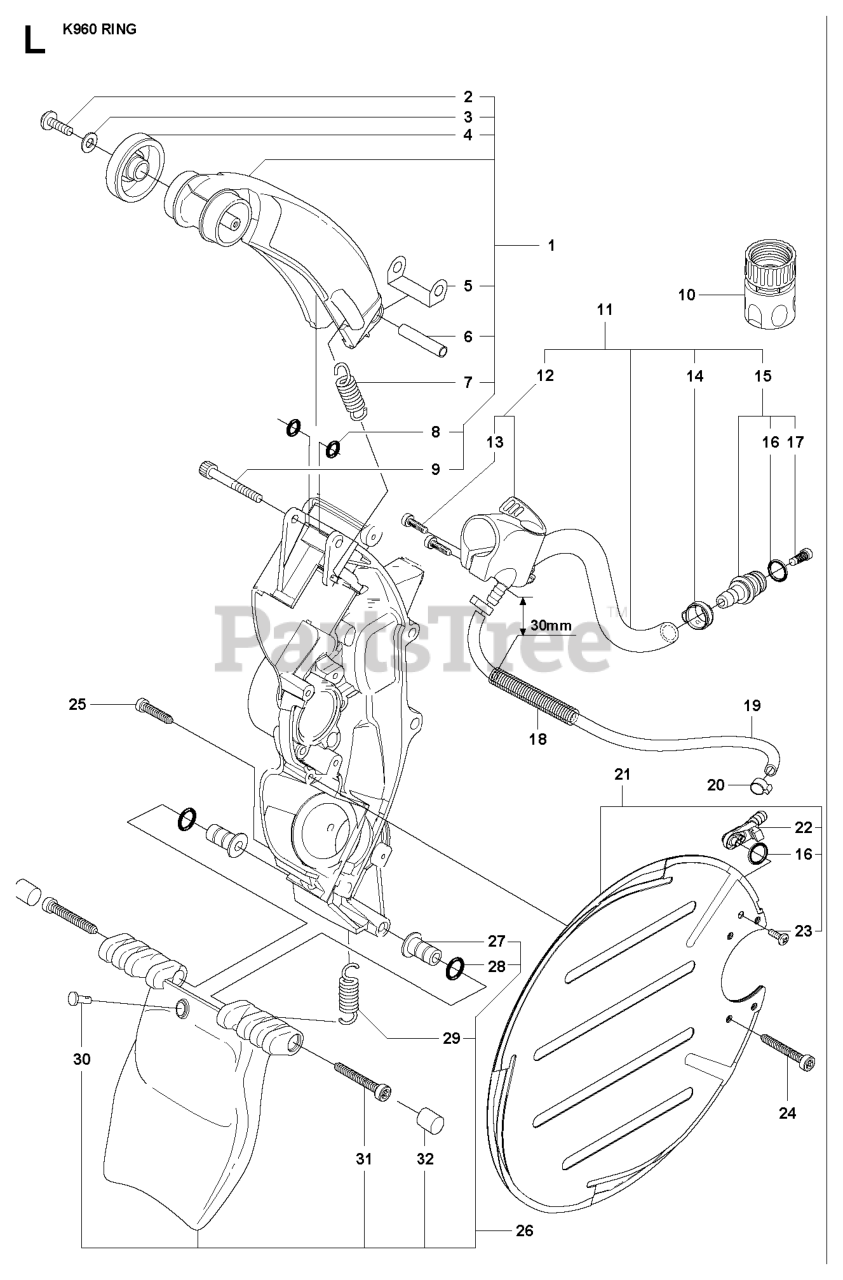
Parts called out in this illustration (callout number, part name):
2	SCREW PW5X14 10.9
9	SCREW ITXSCM
10	FEMALE QUICK COUPLER
11	RP HOSE
12	VALVE ASSY
14	RP CLAMP
15	NIPPLE
16	RP O-RING
19	HOSE KIT
20	HOSE CLAMP
31	SCREW ITXSCM M6X37/25 T27 12.
